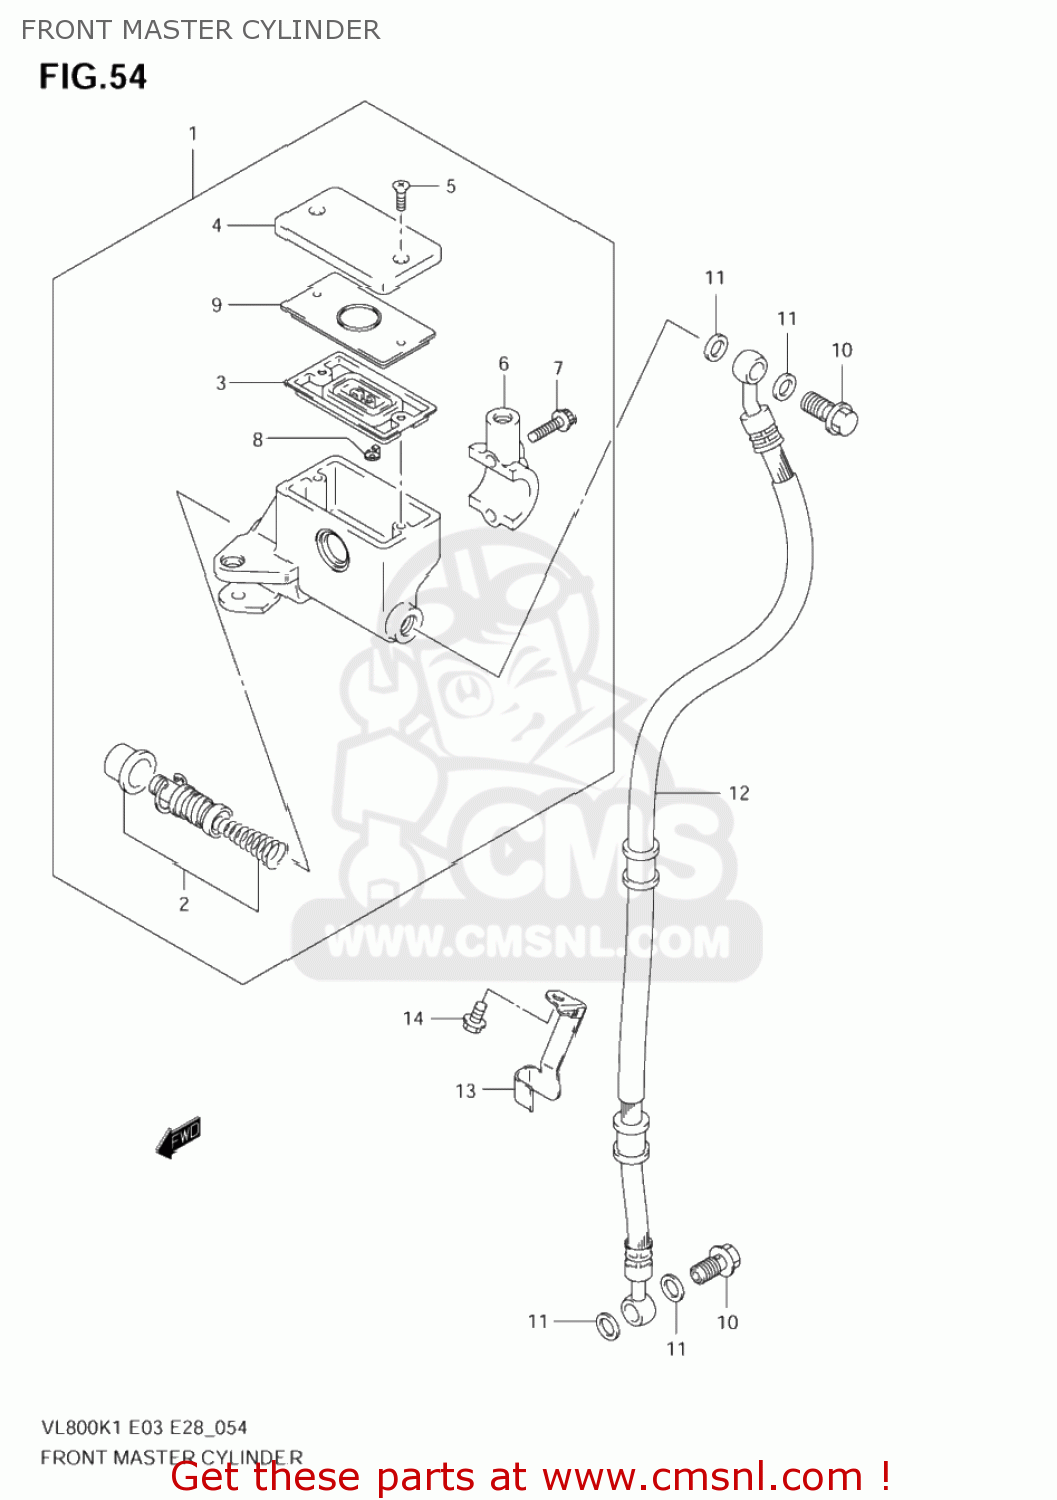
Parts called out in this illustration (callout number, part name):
1	CYLINDER ASSY,FR MASTER
2	PISTON/CUP SET
3	4
4	CAP
5	SCREW
6	HOLDER
7	BOLT
8	PROTECTOR
9	PLATE,DIAPHRAGM
10	BOLT UNION
11	WASHER(10X15X1.5)
12	HOSE,FRONT BRA
13	CLAMP,FR BRAKE HOSE UPR
14	BOLT
